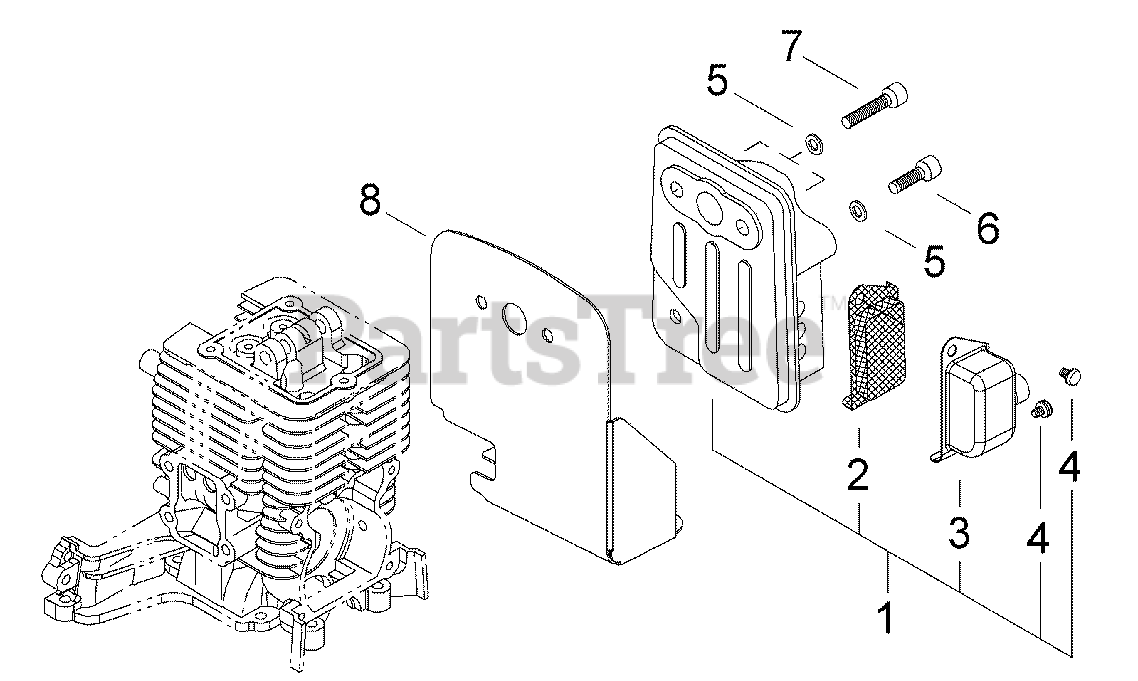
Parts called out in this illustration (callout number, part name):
1	MUFFLER ASSY
2	SCREEN, SPARK ARRESTOR
3	GUIDE, EXHAUST
4	SCREW - 4X6
5	WASHER - 5
6	SCREW - 5X16
7	SCREW - 5X25
8	DEFLECTOR, HEAT
